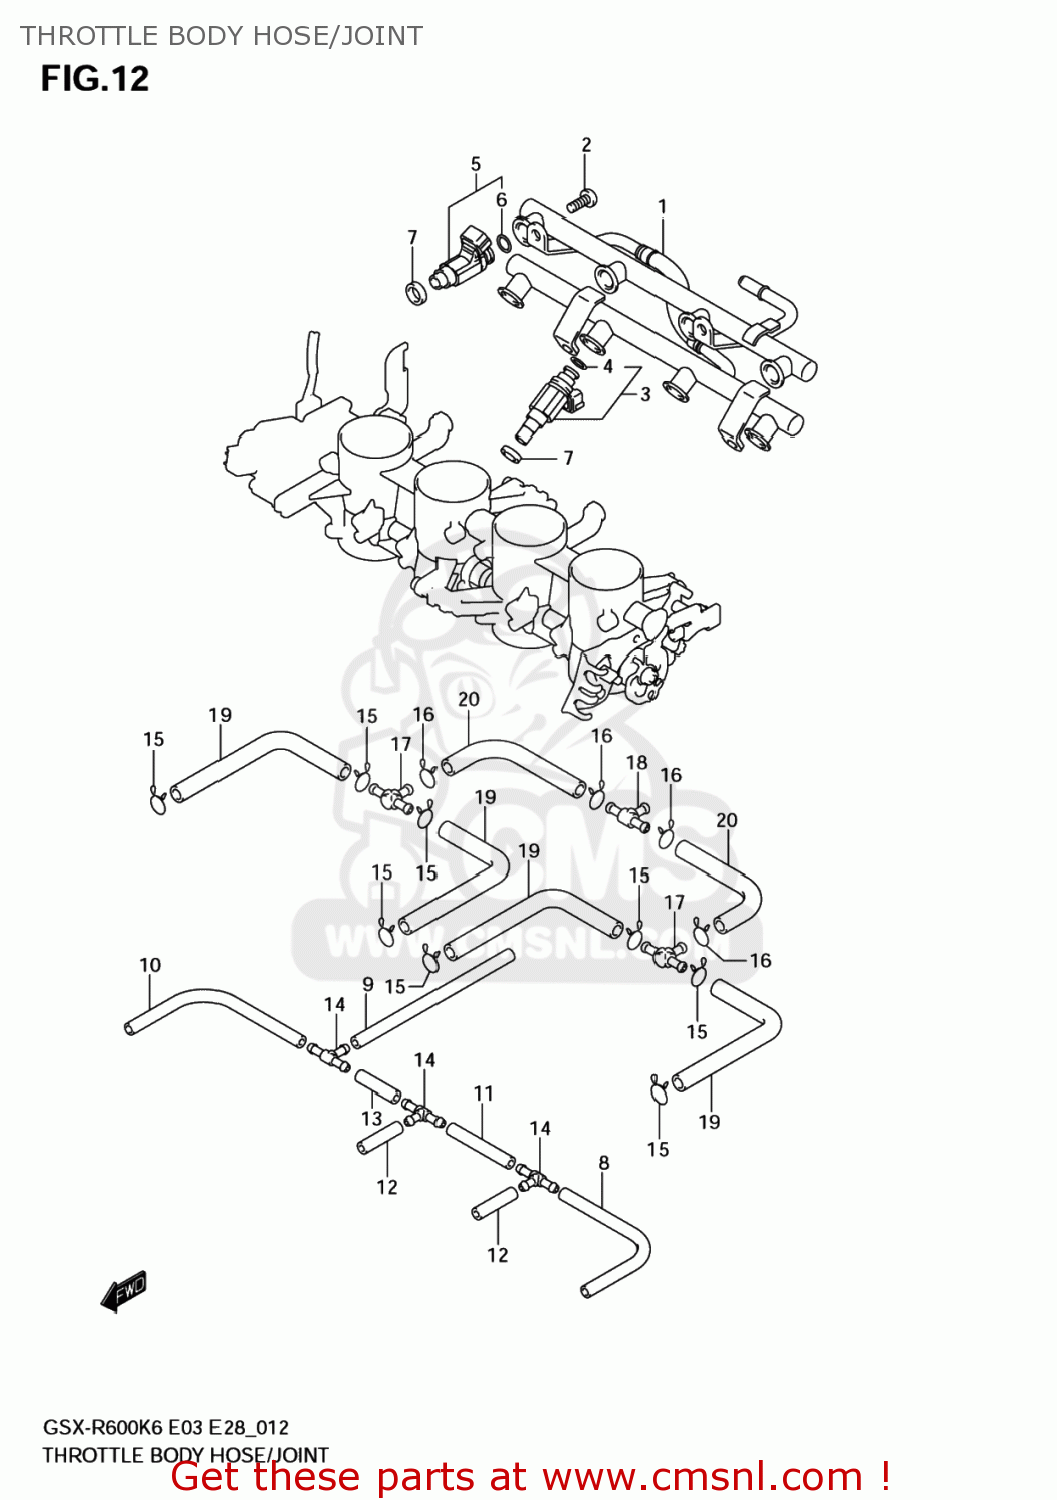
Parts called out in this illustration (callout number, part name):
1	DELIVERY PIPE ASSY
2	SCREW
3	INJECTOR ASSY
4	O RING
5	INJECTOR ASSY
6	O RING
7	SEAL
8	HOSE
9	HOSE
10	HOSE(L:425)
11	HOSE(3.2X7.4X225)
12	HOSE(L:425)
13	HOSE(L:425)
14	3WAY,VACUUM HOSE
15	CLIP
16	CLIP
17	NIPPLE
18	NIPPLE
19	HOSE
20	HOSE
